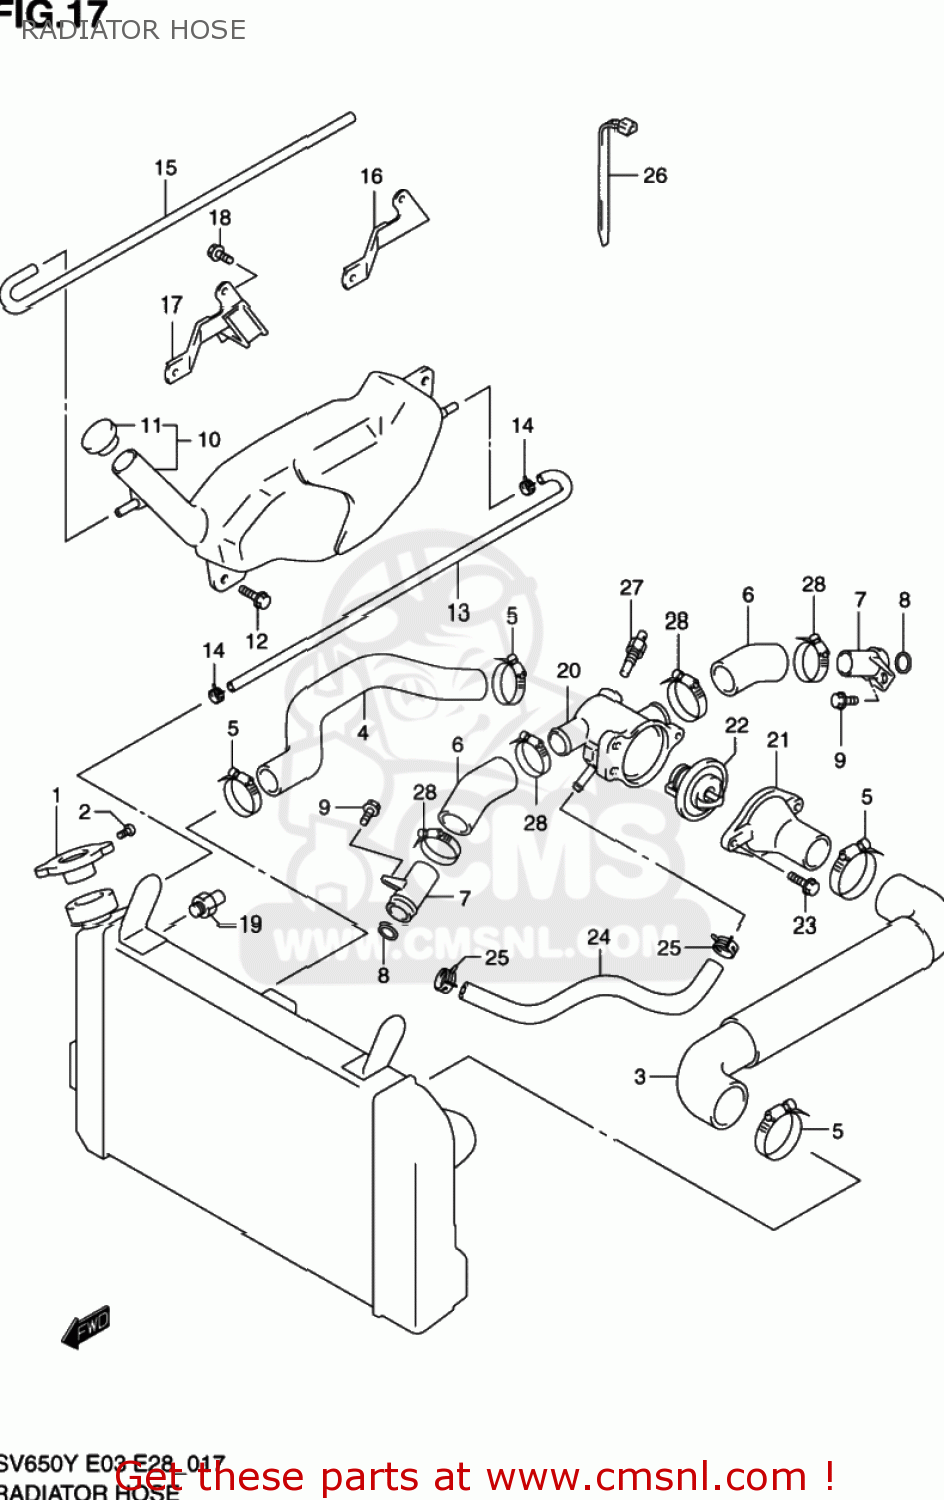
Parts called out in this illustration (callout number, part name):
1	CAP COMP,RADIATOR
2	SCREW,RADIATOR CAP
3	HOSE,RADIATOR INLET
4	HOSE,RADIATOR OUTLET
5	CLAMP
6	HOSE,CONNECTOR INLET
7	UNION,CONNECTOR HOSE
8	O RING(D:3.2,ID:17.8)
9	BOLT,STRANGER
10	TANK ASSEMBLY,RESERVOIR
11	CAP,RESERVOIR TANK
12	BOLT
13	HOSE,RESERVOIR TANK INLET
14	CLIP
15	HOSE
16	BRACKET,RESERVOIR TANK
17	BRACKET,RSVR T
18	BOLT
19	SWITCH,RADIATOR FAN
20	CONNECTOR,THERMOSTAT,INLET
21	CAP,THERMOSTAT CONNECT
22	THERMOSTAT,WATER 82 DEG
23	BOLT
24	HOSE,CONNECTOR TO WATER PUMP
25	CLAMP
26	CLAMP(L:125)
27	WATER TEMPERATU
28	CLAMP
